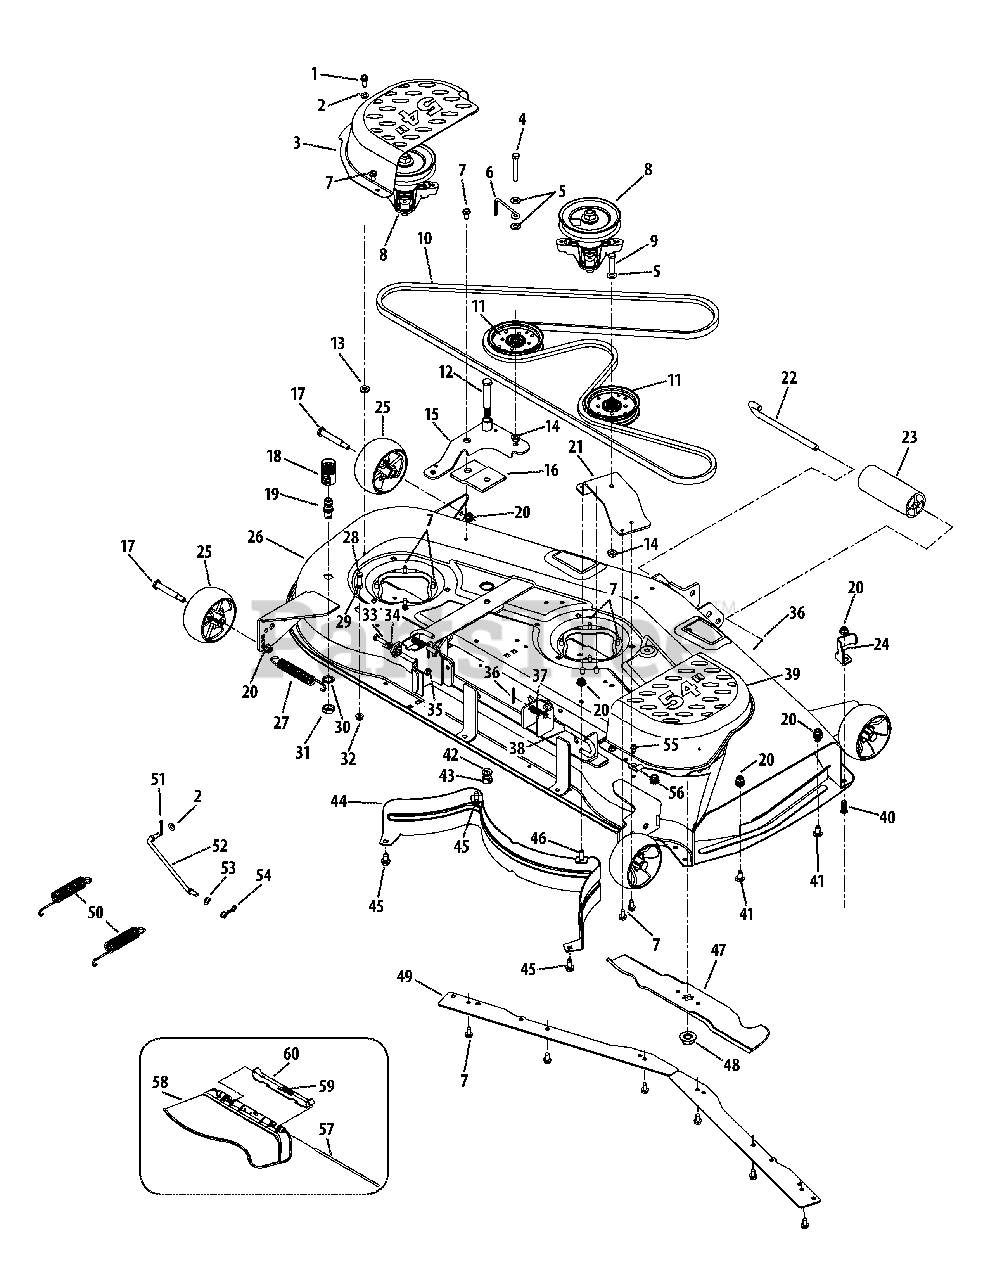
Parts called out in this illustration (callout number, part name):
1	Hex Washer Screw, 5.16-18 x .875
2	Flat Washer, .344 x .688 x .065
3	LH Belt Cover
4	Hex Screw, 3.8-16 x 2.50
5	Flat Washer, .406 x .875 x .059
6	Belt Keeper Rod
7	Hex Washer Screw, 5.16-18
8	Spindle Assembly
9	Hex Screw, 3.8-16 x 1.75
11	Idler Pulley
12	Shoulder Screw, 1.2-13 x .625 x 2.50
13	Flat Washer, .407 x .812 x .135
14	Flange Lock Nut, 3.8-16
15	Idler Assembly Arm
16	Pulley Stabilizer Bracket
17	Shoulder Bolt, 3.8-16 x .496 x 2.50
18	Water Nozzle Adapter
19	Deck Water Nozzle
20	Flange Lock Nut, 3.8-16
21	Stationary Idler Bracket
22	Roller Pin, 1.2 x 7.31
23	Front Roller
24	Chute Deflector Stop
25	Deck Wheel
26	Deck Assembly
27	Extension Spring, .850 x 6.415
28	Hex Screw, 5.16-18 x 2.00
29	Hex Nut, 5.16-18
30	Lock Washer, 5.8
31	Hex Nut, M16-1.5
32	Flange Lock Nut, 5.16-18
33	Hex Screw, 5.16-18 x 1.25
34	Deck Adjustment Gear
35	Deck Hanger Bracket Assembly
36	Cotter Pin, 3.32 x 1.0
37	Compression Spring, .531 x 1.75
38	Deck Release Rod
39	RH Belt Cover
40	Hex Screw, 3.8-16 x 1.00
41	Carriage Bolt, 3.8-16 x .75
42	Lock Washer, 1.2
43	Hex Lock Nut, 1.2-13
44	Inner Baffle
45	Hex Washer Screw, 3.8-16 x .750
46	Carriage Bolt, 3.8-16 x 1.00
47	Blade, 18.5
48	Flange Nut, 5.8-18
50	Extension Spring, 1.010 x 6.500
51	Cotter Pin, 1.8 x 1.25
52	Deck Support Rod
53	Washer, .375 x .70 x .030
54	Bow-Tie Cotter Pin
55	Hex Washer Screw, 1.4-20 x .500
56	Hook Retainer Bracket
57	Hinge Pin, .3175 x 14.06
58	Chute Assembly
59	Torsion Spring, .44 x 2.0
60	Chute Bracket
